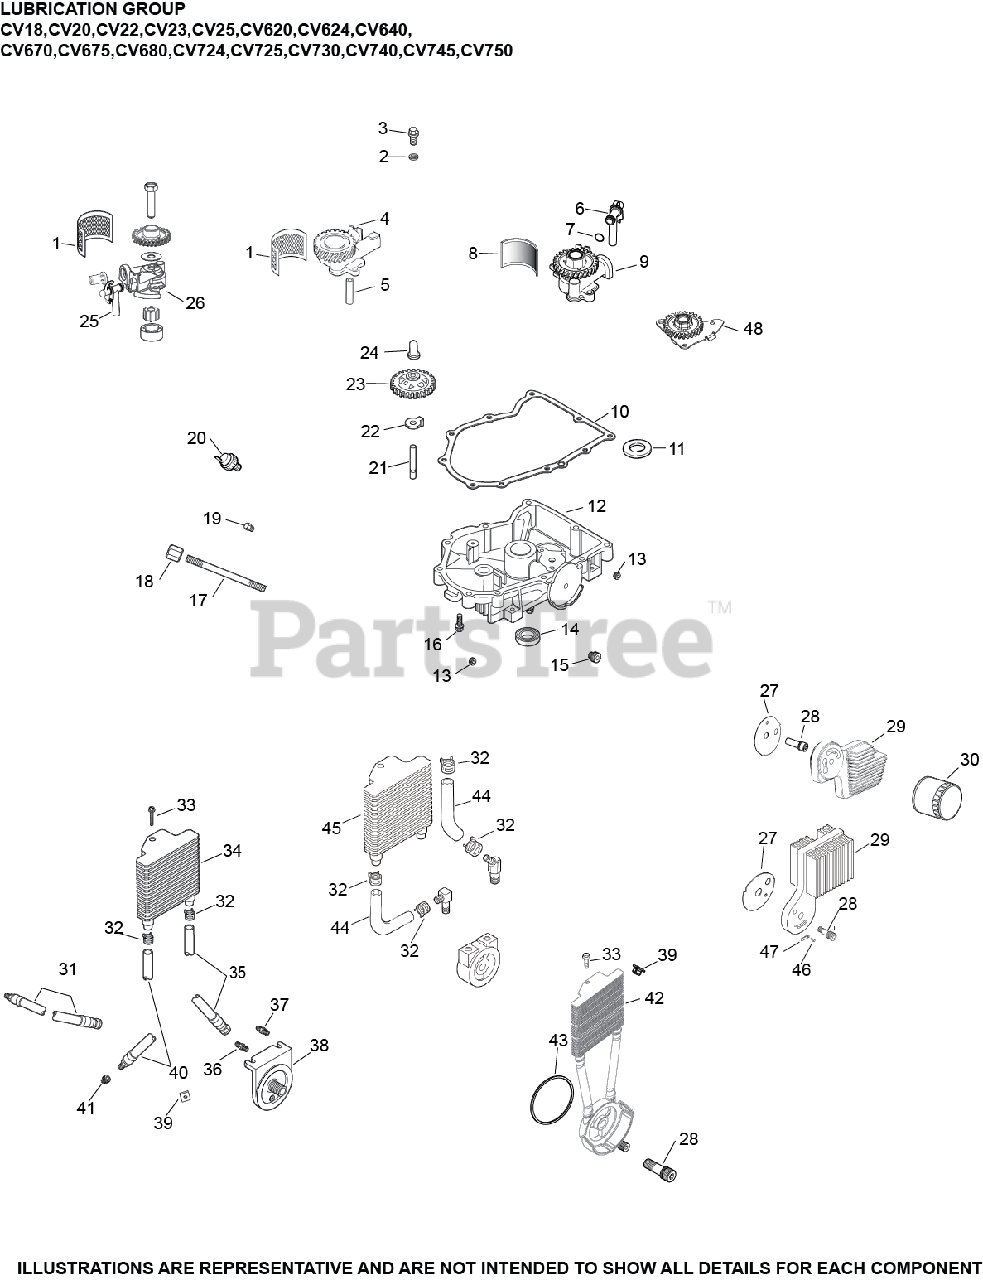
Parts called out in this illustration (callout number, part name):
10	GASKET, OIL PAN
12	KIT, OIL PAN ASSEMBLY
13	PLUG, PIPE CTSK 3/8"
14	SEAL, OIL
16	SCREW, FLG M8X1.25X45
20	SENSOR, OIL PSI
21	SHAFT, GOVERNOR GEAR
22	TAB, LOCKING
23	KIT, GOVERNOR GEAR W/PIN
24	PIN, GOVERNOR REGULATING
30	OIL FILTER
48	PUMP ASSEMBLY, OIL USE 24 393 89-S
